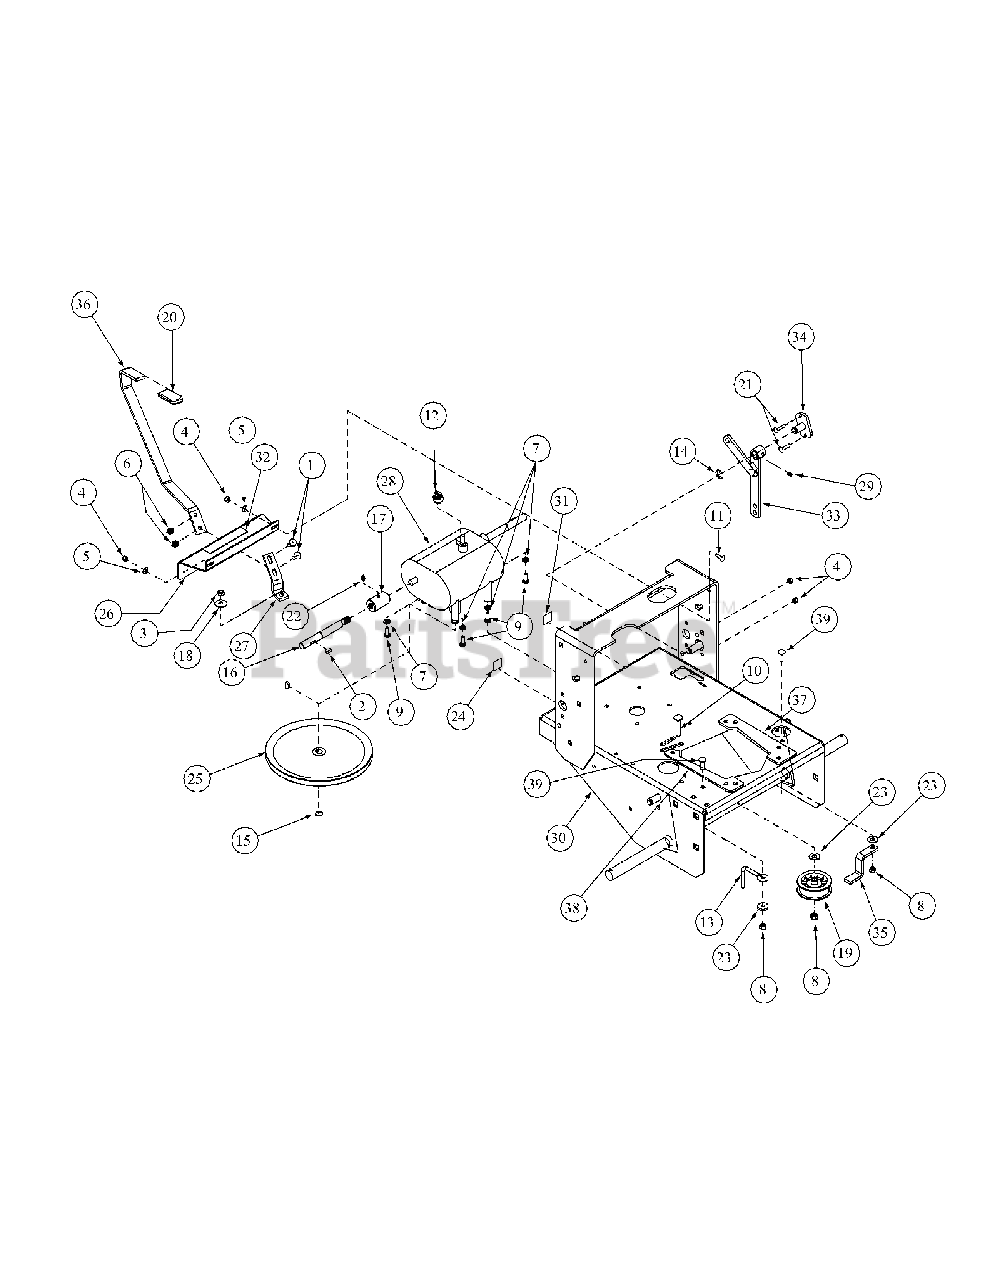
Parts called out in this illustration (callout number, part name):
1	Carriage Bolt, 5/16-18 x 1
2	Woodruff Key, 3/16 x 3/4
3	Jam Nut, Insert Lock, 3/8-24
4	Lock Nut, Nylon Insert, 1/4-20
5	Flat Washer, 1/4 Zinc
6	Nut, 5/16-18 Nylock
7	Lock Washer, 5/16 Zinc
8	Lock Nut, Nylon Insert, 3/8-16
9	Hex Cap Screw, 5/16-18 x 3/4
10	Carriage Bolt, 3/8-16 x2
11	Carriage Bolt, 1/4-20 x .750
12	Switch, WB Transmission
13	Drive Belt Guide
14	E-Ring, 5/8
15	External Retainer Ring
16	Jackshaft w/ Heavy Spline
17	Coupling w/Heavy Spline
18	Bell Washer, .39 ID x 1.13 OD x .062
19	Flat Idler Pulley w/Adapter
20	Grip, .250 x 1 x 3-1/2, Yellow
21	Carriage Bolt, 1/4-20 x 1.00
22	Grease Fitting, 1/4-28 x 3/16
23	Idler Washer
24	Decal "Made In America
25	Transmission Pulley
27	Shift Arm
28	Transmission, 5 Speed
29	Grease Fitting, 1/4-28 x 1/2
30	Engine Deck Assembly
31	Label, Warning, Open Belt Drive
32	Label, Mower Instruction
33	Clutch, Bellecrank Weldment
34	Bellecrank Pivot, Weldment
35	Engine Belt Guide
37	Engine Spacer, LH
38	Engine Spacer, RH
39	Carriage Screw, 3/8-16 x 1.25
